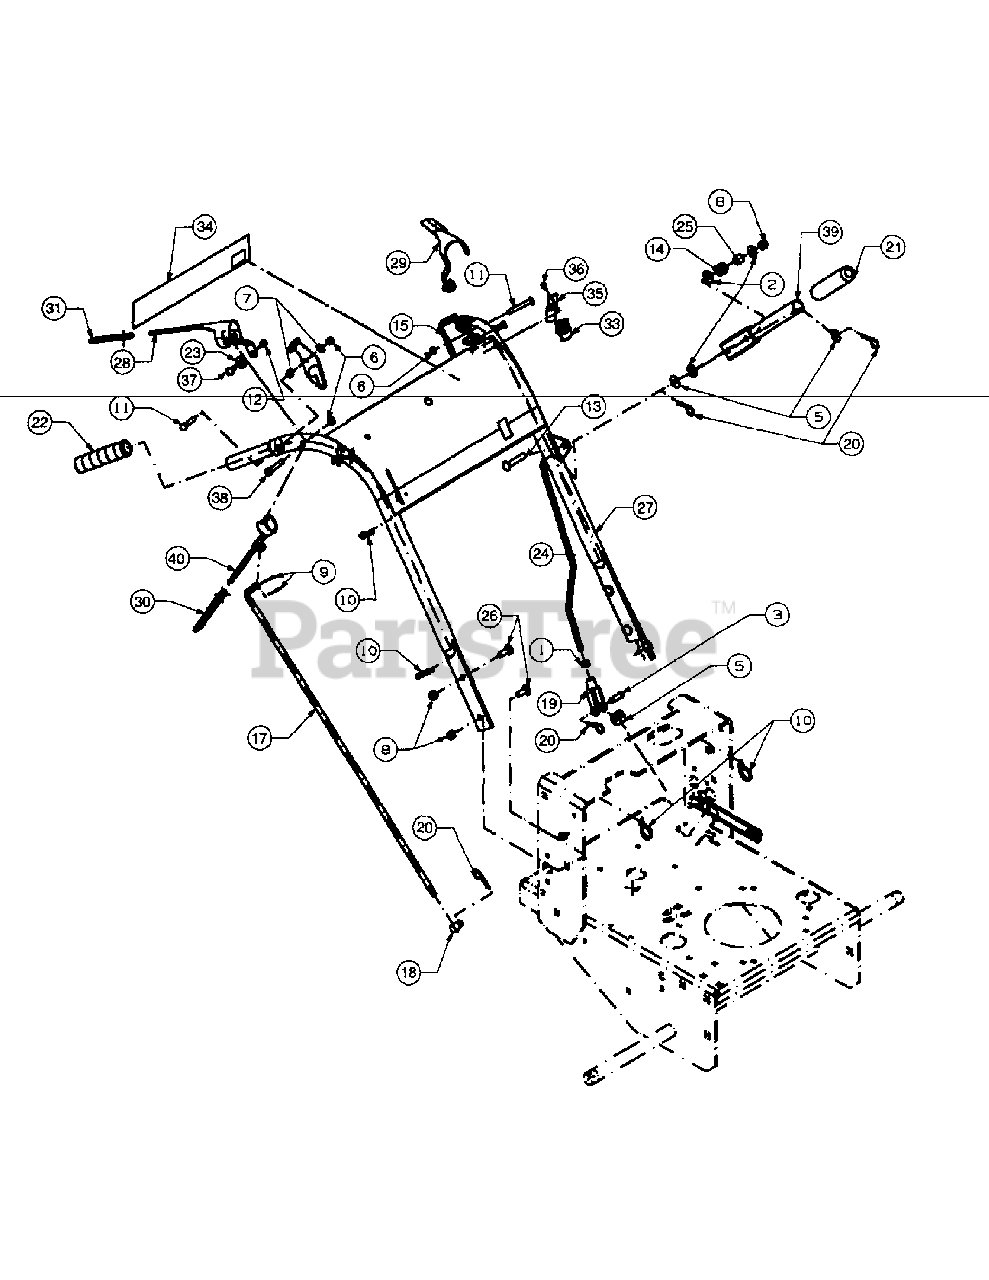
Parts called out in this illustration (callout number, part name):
1	Hex Nut, 3/8-16
2	Flat Washer, 3/8 Zinc
3	Clevis Pin, 3/8 x 1-1/8 Zinc
4	Grip, Neutral Latch, 1.25"
5	Flat Washer, 3/8 Zinc
6	Nylock Nut, 5/16-18
7	Flat Washer, 5/16 Zinc
8	Lock Nut, Nylon Insert, 3/8-16
9	Cotter Pin, 3/32 x 3/4, Zinc
10	Cable Tie, 3/16 x. 05 x 7.4
11	Hex Cap Screw, 5/16-18 x 2
12	Lock Nut, Nylon Insert
13	Carriage Bolt, 3/8-16 x 2
14	Spring, .850 OD x 1
15	Neutral Latch, Left Hand
15	Neutral Latch, Right Hand
17	Steering Control Rod
18	Joint Swivel
19	Yoke, 3/8-16 Female
20	Hair Pin 3/8-1/2
21	Handle Grip, Black, 1"
22	Plastic Handle Grip, Black, 4-5/8
23	Control Rod, Hydro Spacer
24	Hydro Blade Clutch Rod Base
25	Spring Sleeve
26	Carriage Bolt, 3/8-16 x 2
27	Handle Assembly Hydro
28	Operator Presence Control RH
29	Operator Presence Control LH
30	Control Sleeve, Black
31	Operator Control Sleeve, Yellow
32	Harness Assembly Adapter
33	Switch Mounting Snap
34	Handle Label, Rear, 5 Speed
35	Operator Presence Return Spring
36	Hex Index Washer Screw, 0.500
37	Shoulder Screw, .38 x .412, 1/4-28
38	Hex Cap Screw, 5/16-18, 2.00
39	Blade Clutch Lever
40	Lever Assembly Control
